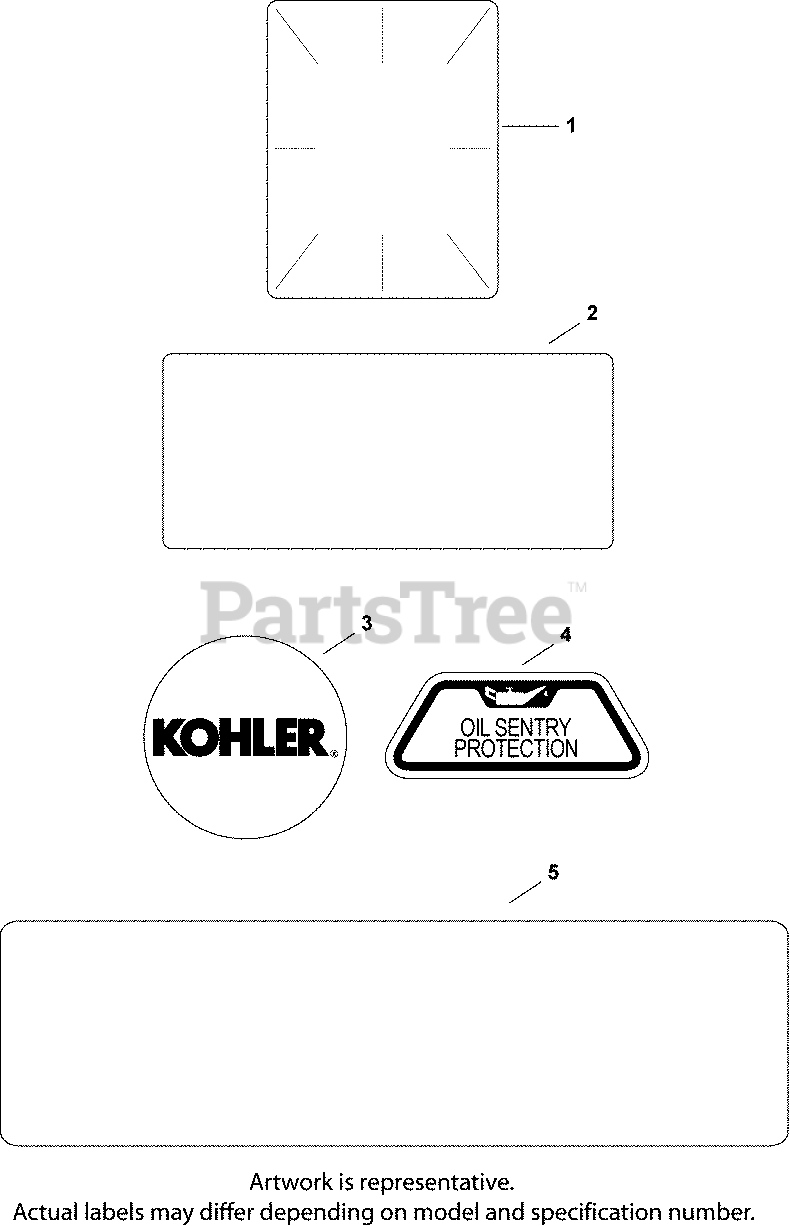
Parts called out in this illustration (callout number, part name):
1	DECAL, CLEAR LAMINATE USE 25 113 70-S
2	DECAL, REPL ENGINE(NONCERT)
3	DECAL, GRASS SCREEN USE 24 113 499-S
4	DECAL, OIL SENTRY - (#DSC)
5	DECAL, 25 HP - DISCONTINUED
